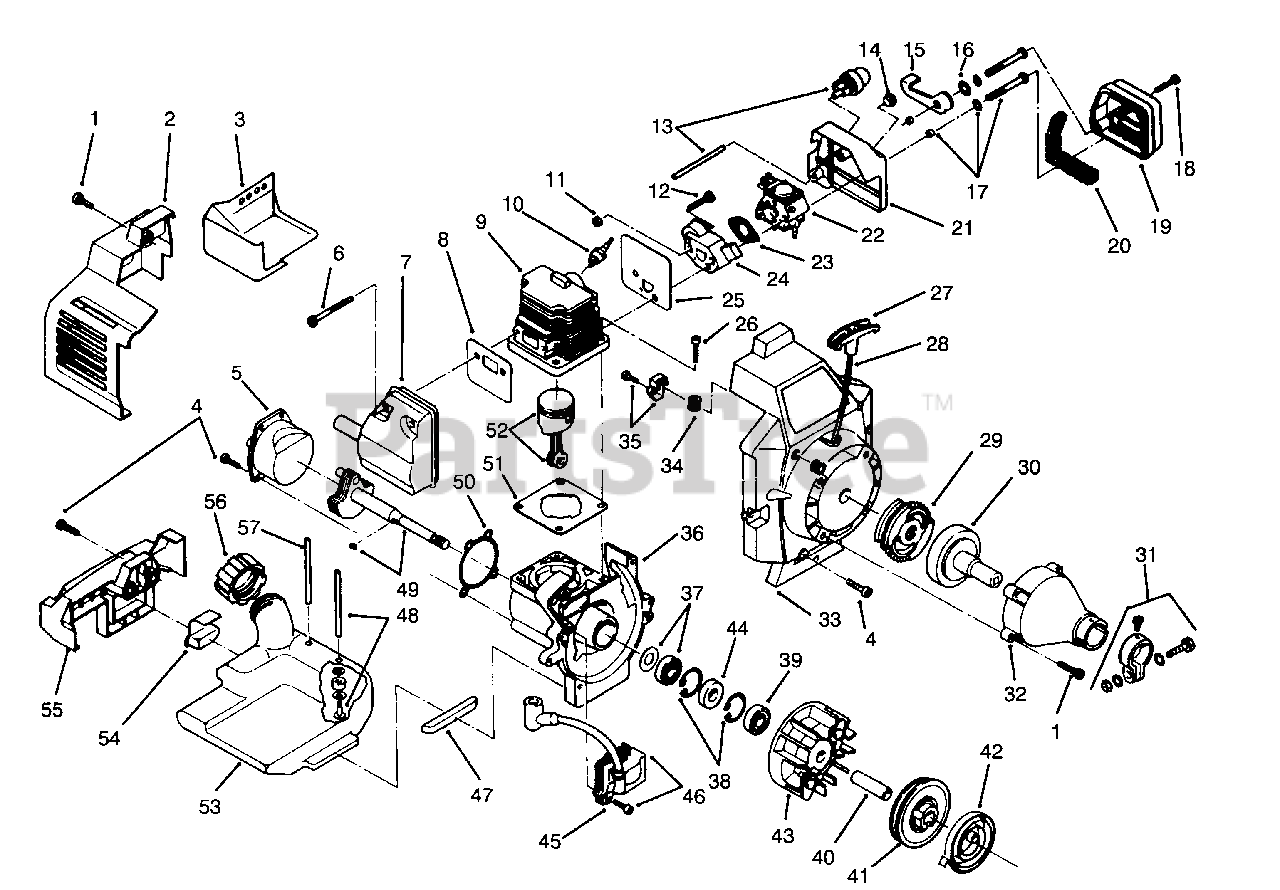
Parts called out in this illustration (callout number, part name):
2	Cover-Rear
3	Shield-Heat
4	Screw-Mounting
5	Cap-Crankcase (Incl. Ref. No. 4)
6	Screws-Muffler Mounting
7	Assembly-Muffler (Incl. Ref. No. 8)
8	Gasket-Muffler
9	Cylinder (Incl. Ref. No. 51)
10	Spark Plug
11	Spacer Nut Set
12	Spacer Screw Set
13	Primer Bulb and Hose
14	Switch-Plug
15	Lever-Choke
16	Washer-Wave
17	Assy.-Screw, Carb. Mount
18	Screw
19	Cover-Air Cleaner
20	Element-Air Filter
21	Assy.-Base, Air Cleaner
22	Assembly-Carburetor (Incl. Ref. No. 23)
23	Gasket-Carb. (10 Pack)
24	Assembly-Spacer, Carb. (Incl. Ref. No. 11 & 12)
25	Gasket-Cylinder/Carb.
27	Handle-Pull
28	Rope-Starter
29	Assembly-Rotor Clutch
30	Assembly-Clutch Drum
31	Assembly-Clamp
32	Assembly-Housing, Clutch (Incl. Ref. No. 1)
33	Assembly-Housing (Incl. Ref. No. 4)
34	Guide-Rope
35	Retainer-Pulley
36	Assembly-Crankcase (Incl. Ref. No. 5, 37-39, 44, & 49-50)
37	Assembly-Bearing, Inner
38	Assembly-Snap Ring
39	Bearing-Outer
41	Pulley-Recoil
42	Spring-Recoil
43	Assembly-Flywheel
45	Tab-Ground
46	Assembly-Module
47	Pad-FuelTank,Front
48	Assembly-Fuel Line
49	Assembly-Power Shaft
50	Gasket-Cap, Crankcase
51	Gasket-Cylinder
52	Assy.-Piston and Rod
53	Assembly-Fuel Tank
54	Pad-Fuel Tank, Rear
55	Bracket-Fuel Tank
56	Cap-Fuel Tank
57	Fuel Line-Return
